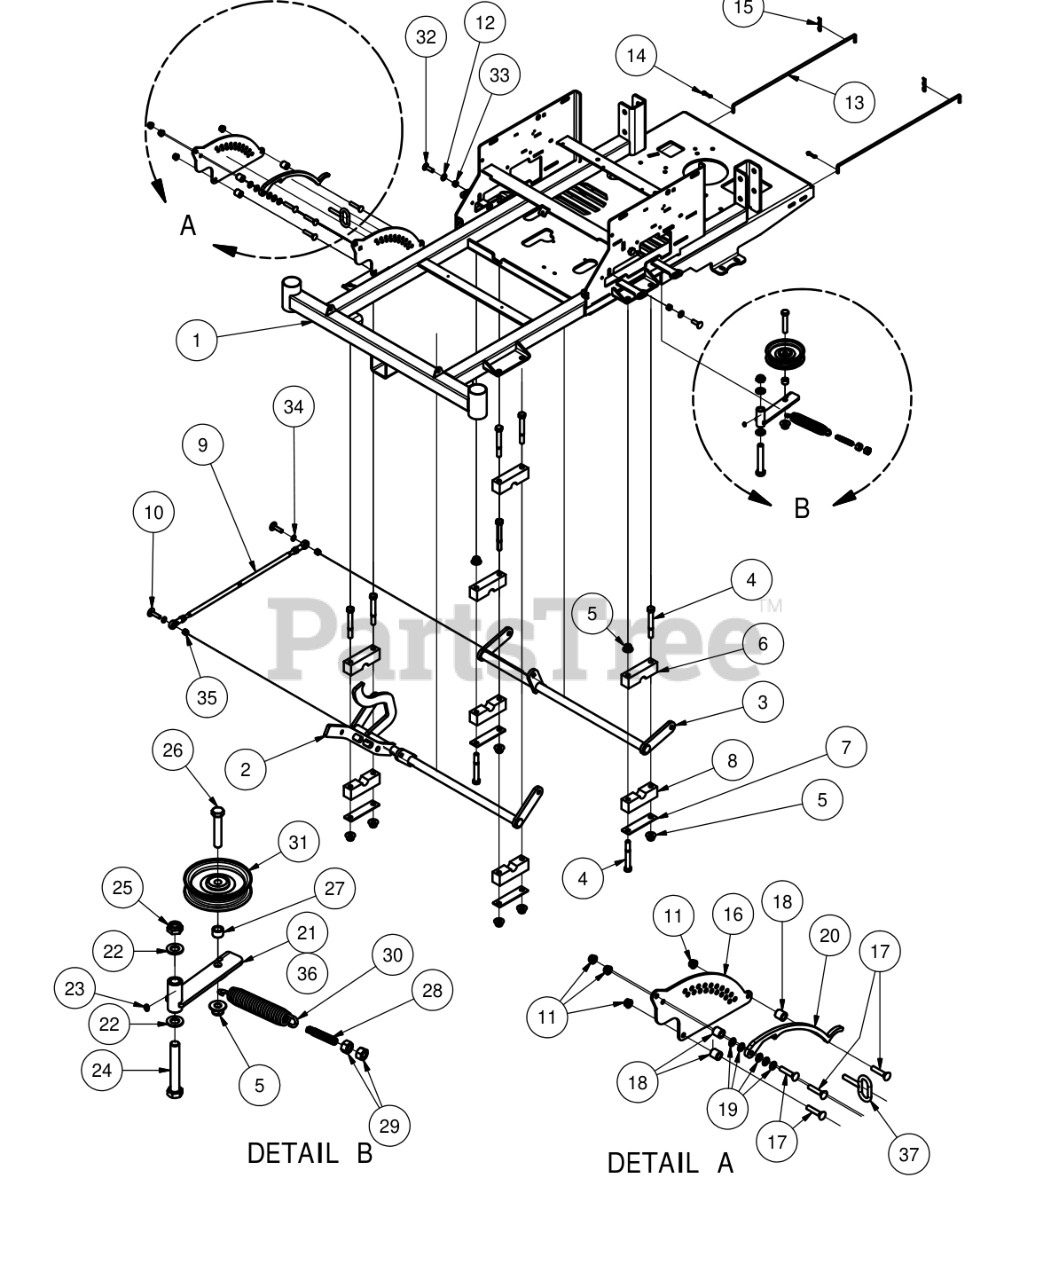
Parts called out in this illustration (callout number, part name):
1	2016 Compact Outlaw Frame
2	Actuator Bar Front- 2016 Compact Outlaw
3	Actuator Bar Rear- 2016 Compact Outlaw
4	1/2" x 4" Bolt (Grade 8)
5	1/2-13 Nylon Flange Nut
6	Two Piece Pillow Block (Male)
7	Two Piece Pillow Block Strap
8	Two Piece Pillow Block (Female)
9	Actuator Bar Linkage Assembly
10	3/8 x 1-1/2 Carriage Bolt
11	3/8" Nylock Flange Nut
12	3/8" Flat Washer
13	ZT Neutral level rod 2011
15	Neutral Rod Clip
16	Outlaw Height Indicator Plate (Outer)
17	3/8 × 1 3/4 Carriage Bolt
18	3/4 OD x 1/2 ID x 3\4 Length
19	.390 x .750 x .062 Nylon Washer
20	Outlaw Deck Lever Lock
21	Pump Idler Bracket
22	.630 ID Plastic Washer
23	1/4" Press in Grease Fitting
24	5/8" x 4" Hex Bolt
25	5/8" Nylock (1/2 Jam)
26	1/2" x 2 3/4" Hex Bolt
27	1/2 x 1/2 Spacer
28	All Thread-Pump Idler Tensioner
29	1/2" Hex Nut
30	2009 Deck/Pump Idler Spring
31	4 3/4" Idler Pulley
32	3/8" x 1 1/4" Carriage Bolt
33	3/8" Hex Nut
34	3/8" Lock Washer
35	3/8 Nylock Nut
36	Pump Idler Assembly (Parts 5,21,24,27,28,and 32)
37	Deck height lever pin
